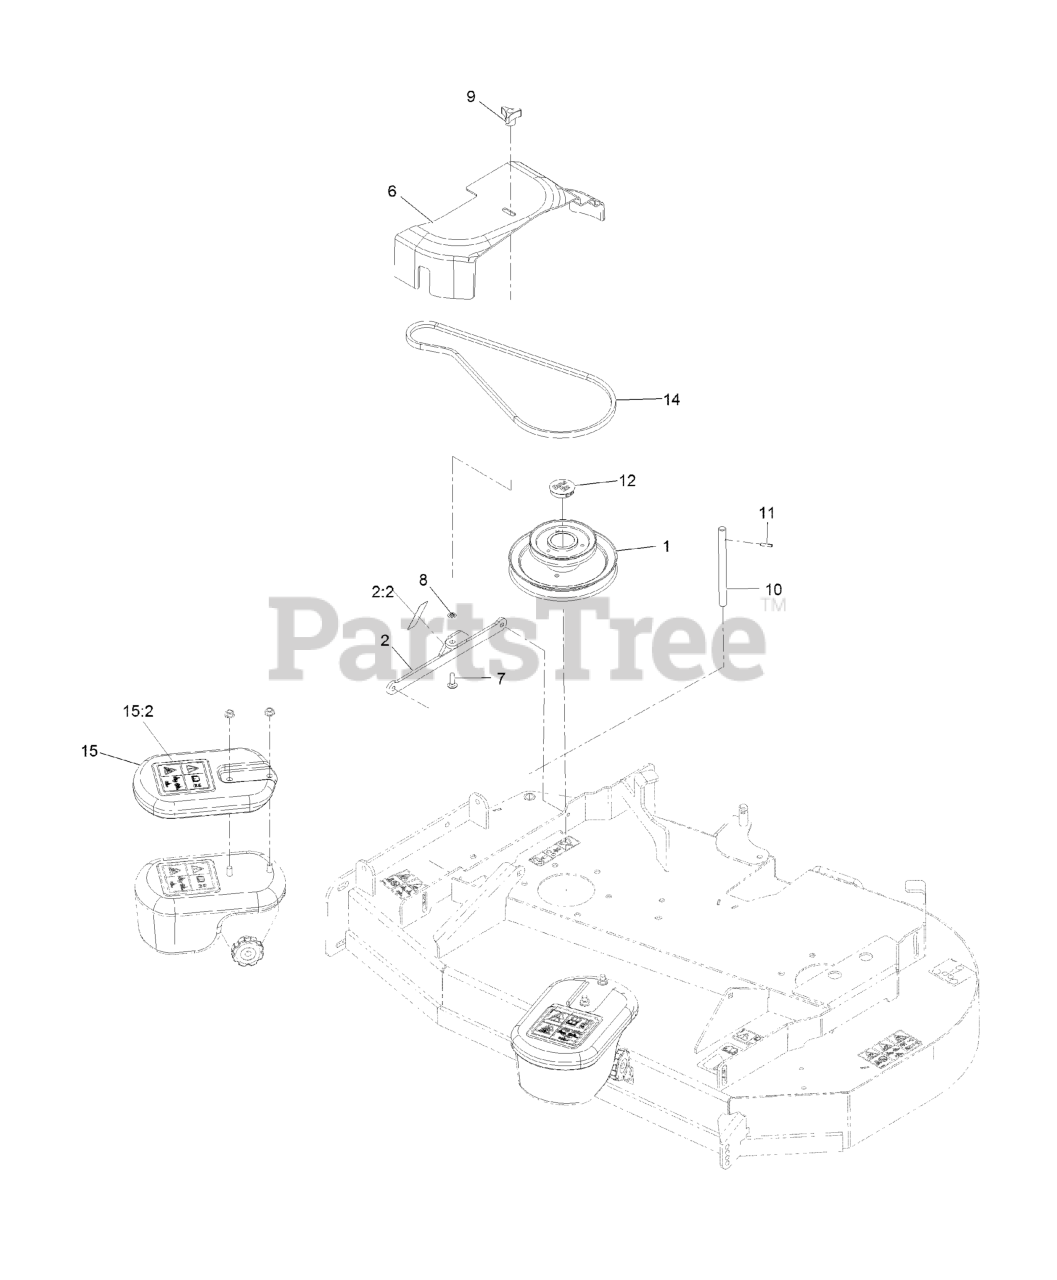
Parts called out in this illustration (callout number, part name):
1	JACKSHAFT- UV DRIVE
2	ASM-CVR BRKT W/DECAL
2:2	DECAL-DANGER
6	COVER-BELT
7	BOLT-CARR
8	RING-RETAINING, BOLT
9	KNOB-3 PRONG
10	SHAFT-CATCHER, GRASS
11	PIN-ROLL
12	PLUG, BLACK NYLON 1.75
15:2	DECAL-WARNING, TRACTION
